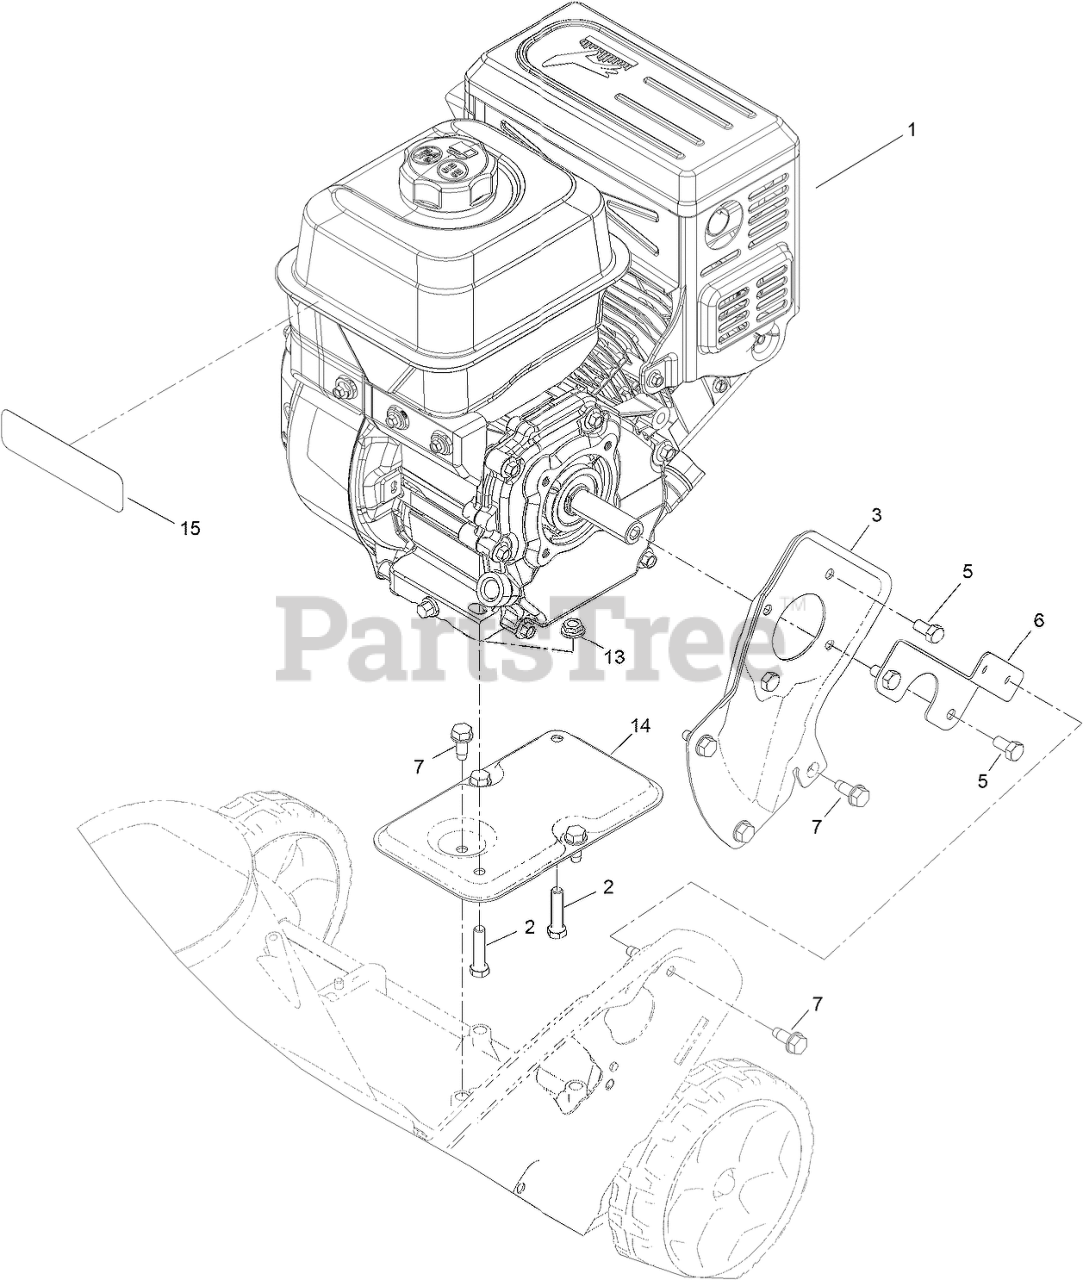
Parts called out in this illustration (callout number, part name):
1	ENGINE - G250FS-4
2	SCREW-HH
3	PLATE-ENGINE, PTO
5	BOLT
6	SUPPORT-ENGINE, SIDE
7	SCREW-THD ROLL, HWH
13	NUT-HF
14	SUPPORT-ENGINE
15	DECAL-ENGINE COMMERCIAL
